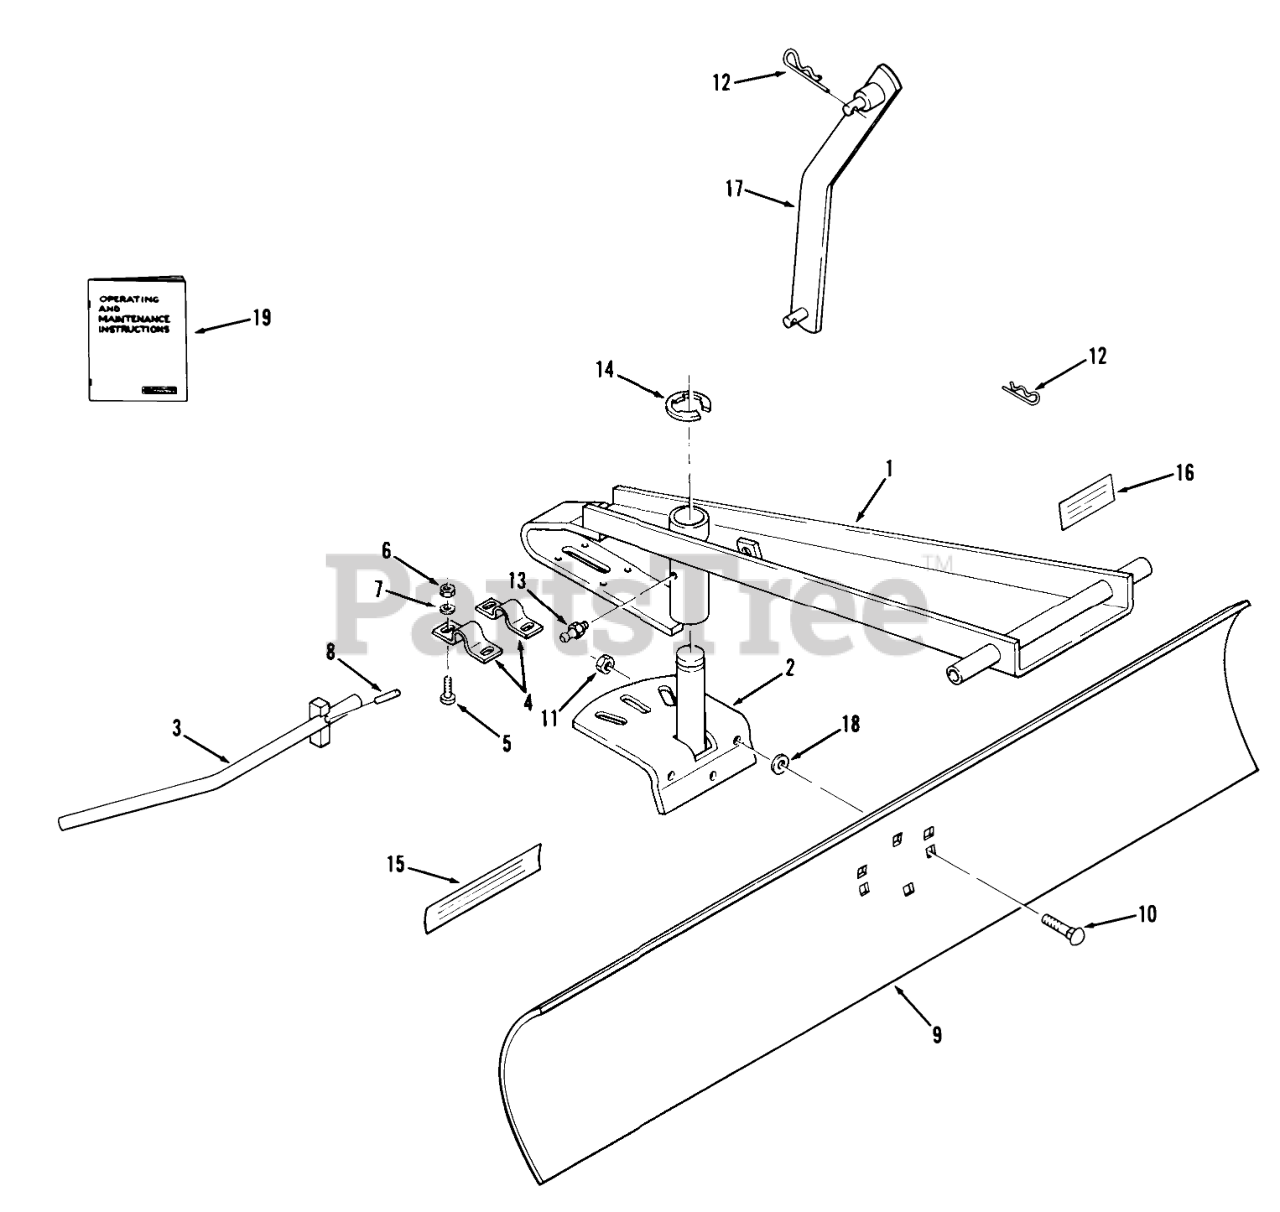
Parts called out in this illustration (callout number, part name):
1	Frame Assembly
2	Blade Support
3	Rod-Angle Adjustment
4	Bracket
5	Screw
6	Nut
7	WASHER
8	PIN-ROLL
9	Blade
10	Bolt
11	Nut
12	Hairpin
13	Zerk
14	E RING
15	DECAL-WHEEL HORSE
16	Caution Decal
17	Lift Link
18	Washer
19	Operating and Maintenance Instructions
